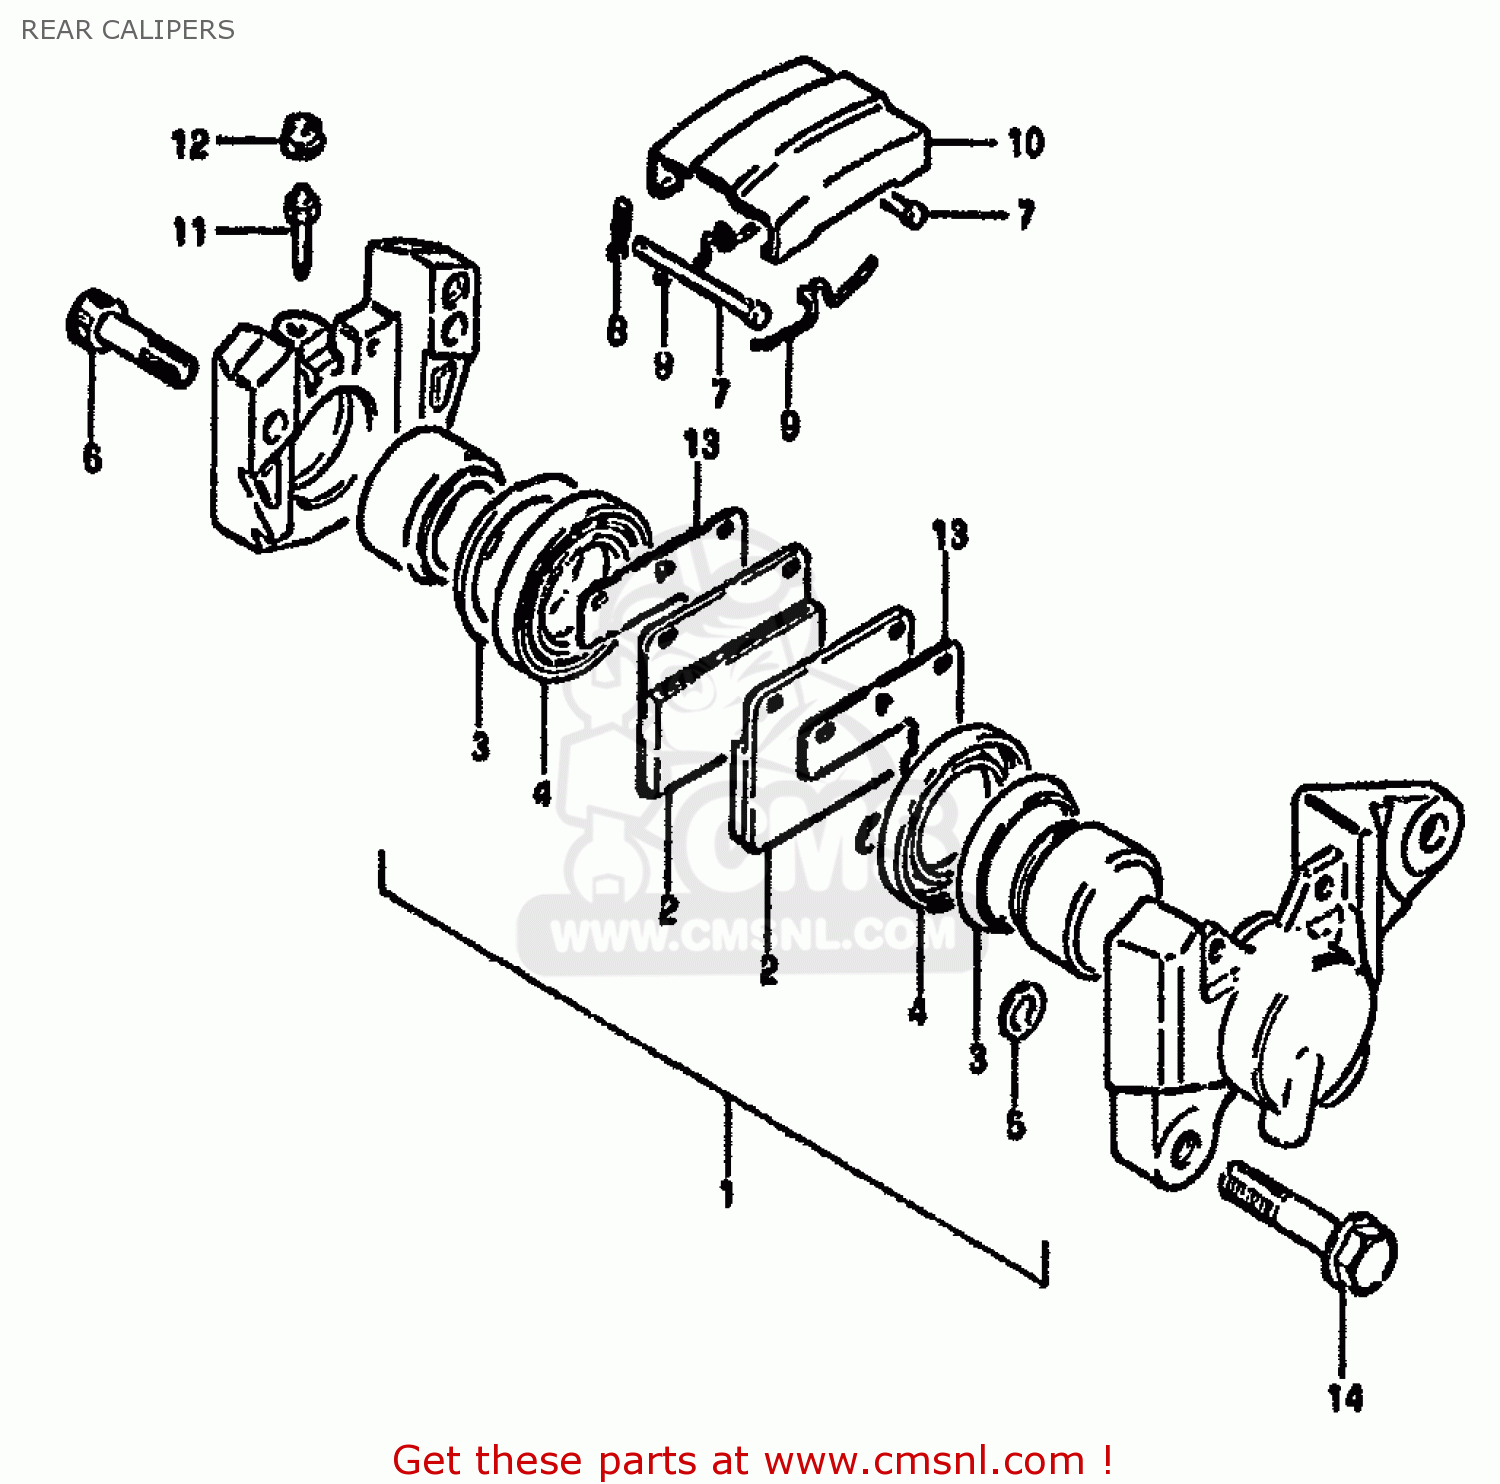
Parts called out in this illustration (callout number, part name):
1	PISTON SET
2	PAD,BRAKE
3	SEAL,PISTON
4	BOOT,PISTON
5	SEAL,JOINT
6	BOLT,CALIPER HOUSING
7	PIN,PAD
8	CLIP,PAD PIN
9	SPRING
10	COVER,DUST
11	BLEEDER
12	CAP,BREATHER
13	SHIM,RR CALIPER
14	BOLT
